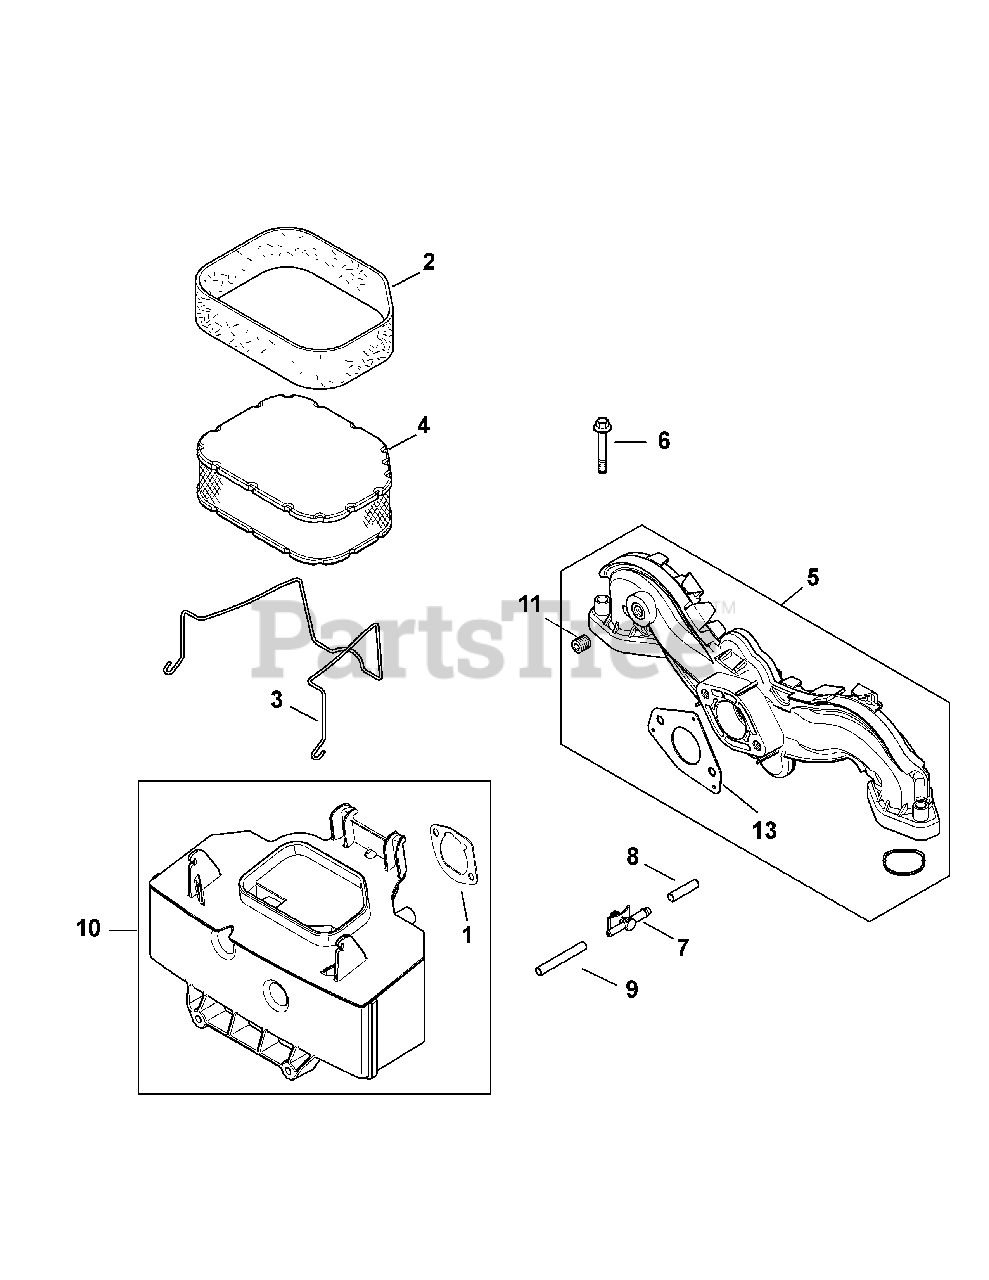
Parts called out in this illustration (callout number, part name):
1	Air Cleaner Base Gasket
2	Pre-Cleaner Element
3	Air Cleaner Element Latch
4	Air & Pre Filter Elements
5	Intake Manifold Kit
6	Flange Screw, M6 x 1.0 x 40
7	Evaporative Connector
8	Evaporative Mask
9	Evaporative Hose, 20"
10	Air Cleaner Base
11	Pipe Plug, 1/8
12	Carburetor Gasket
13	Intake Port O-Ring
